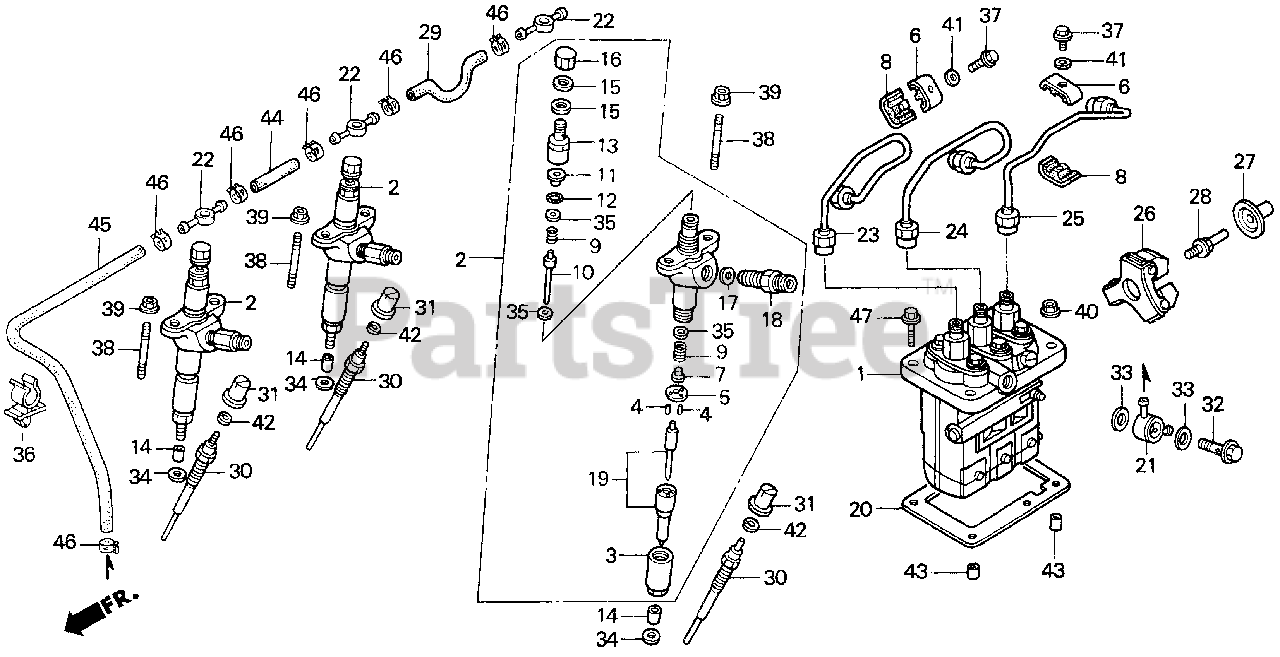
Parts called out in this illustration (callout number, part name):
1	PUMP ASSY., FUEL INJECTION
2	NOZZLE & HOLDER ASSY.
3	NUT, RETAINING
4	PIN (1.78X9.3)
6	HOLDER, FUEL PIPE (A)
7	SEAT, SPRING (A)
8	HOLDER, FUEL PIPE (B)
9	SPRING, NOZZLE
11	SEAT, SPRING (B)
14	COLLAR, NOZZLE
18	CONNECTOR, IN.
20	GASKET A, FUEL INJECTION PUMP (0.5)
20	GASKET B, FUEL INJECTION PUMP (0.3)
20	GASKET C, FUEL INJECTION PUMP (0.1)
21	JOINT, INJECTION PUMP
22	JOINT, FUEL
23	PIPE, FUEL (A)
24	PIPE, FUEL (B)
25	PIPE, FUEL (C)
26	WEIGHT, GOVERNOR
27	SLIDER, GOVERNOR
28	SHAFT, GOVERNOR
29	TUBE, FUEL
30	PLUG, GLOW
31	NUT, GLOW PLUG
32	BOLT, FUEL JOINT
33	WASHER, FUEL JOINT
34	GASKET, NOZZLE
35	SHIM A (0.50)
35	SHIM B (0.51)
35	SHIM C (0.52)
35	SHIM D (0.53)
35	SHIM E (0.54)
35	SHIM F (0.55)
35	SHIM G (0.56)
35	SHIM H (0.57)
35	SHIM I (0.58)
35	SHIM J (0.59)
35	SHIM K (0.60)
35	SHIM L (0.70)
35	SHIM M (0.80)
35	SHIM N (0.90)
36	CLIP, TUBE
37	BOLT, RECESSED (4X18)
38	BOLT 2, STUD (6X32)
39	NUT, FLANGE (6MM)
40	NUT, FLANGE (8MM)
41	WASHER, PLAIN (4MM)
42	WASHER, SPRING (4MM)
43	PIN, DOWEL (6X10)
44	BULK HOSE, FUEL (4.5X3000) (4.5X73)
45	BULK HOSE, FUEL (4.5X3000) (4.5X220)
46	CLIP, TUBE (D8)
47	BOLT, FLANGE (8X22)
